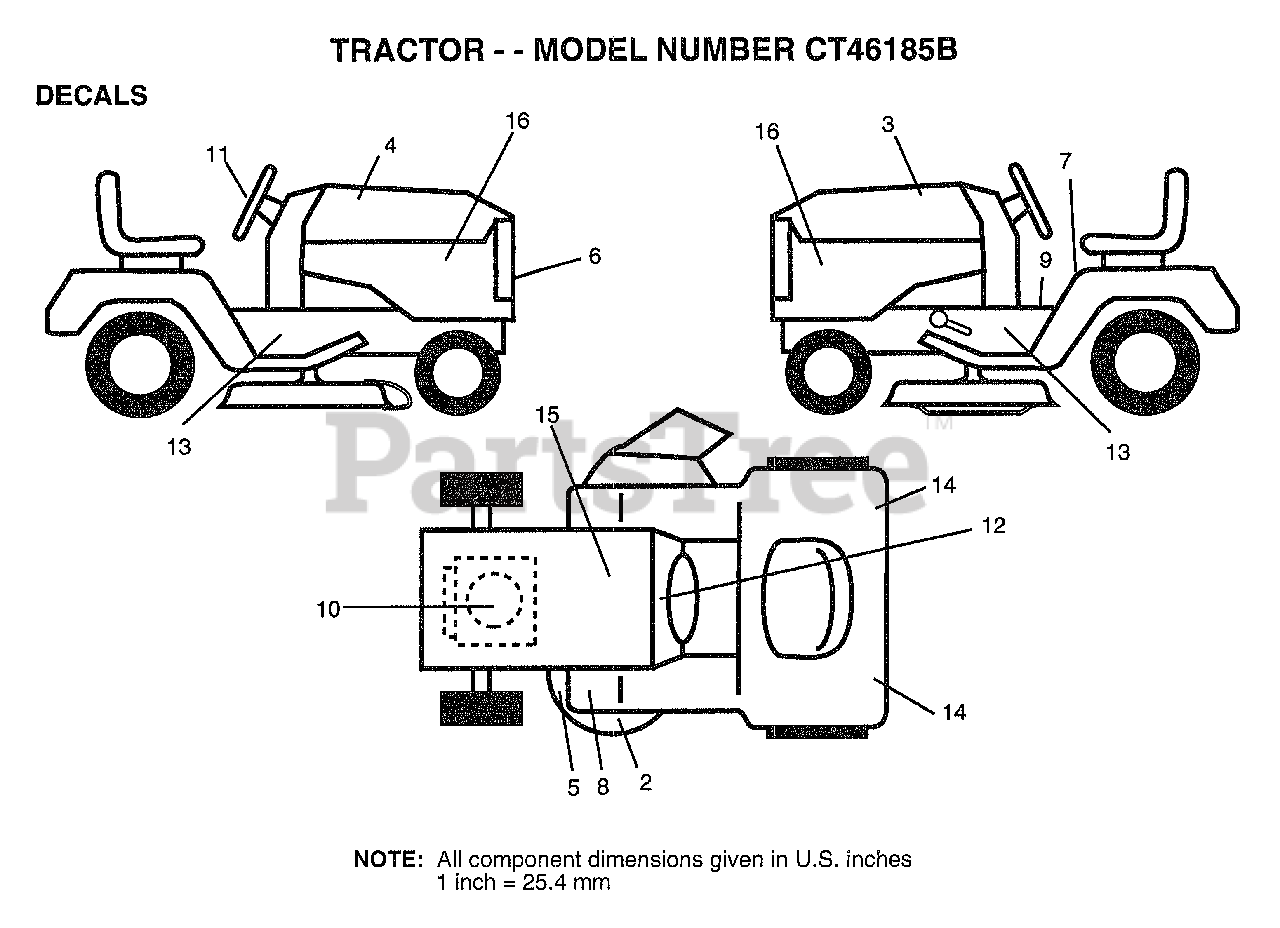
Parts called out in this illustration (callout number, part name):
2	"DECAL,ENVIRO DECK"
3	DECAL.HOOD.LH
4	DECAL.HOOD.RH
5	"DECAL DANGER,FEND"
6	DECAL GRILLE
9	DECAL BRAK PARK
10	DECAL, HP, ENGINE
11	DECAL INST STG WH
12	"DECAL-OPER,GEAR D"
13	DECAL CHASSIS
14	REFLECTOR-TAIL YT
15	DECAL.BATRY.3-3908
16	"DECAL PANEL,SIDE"
